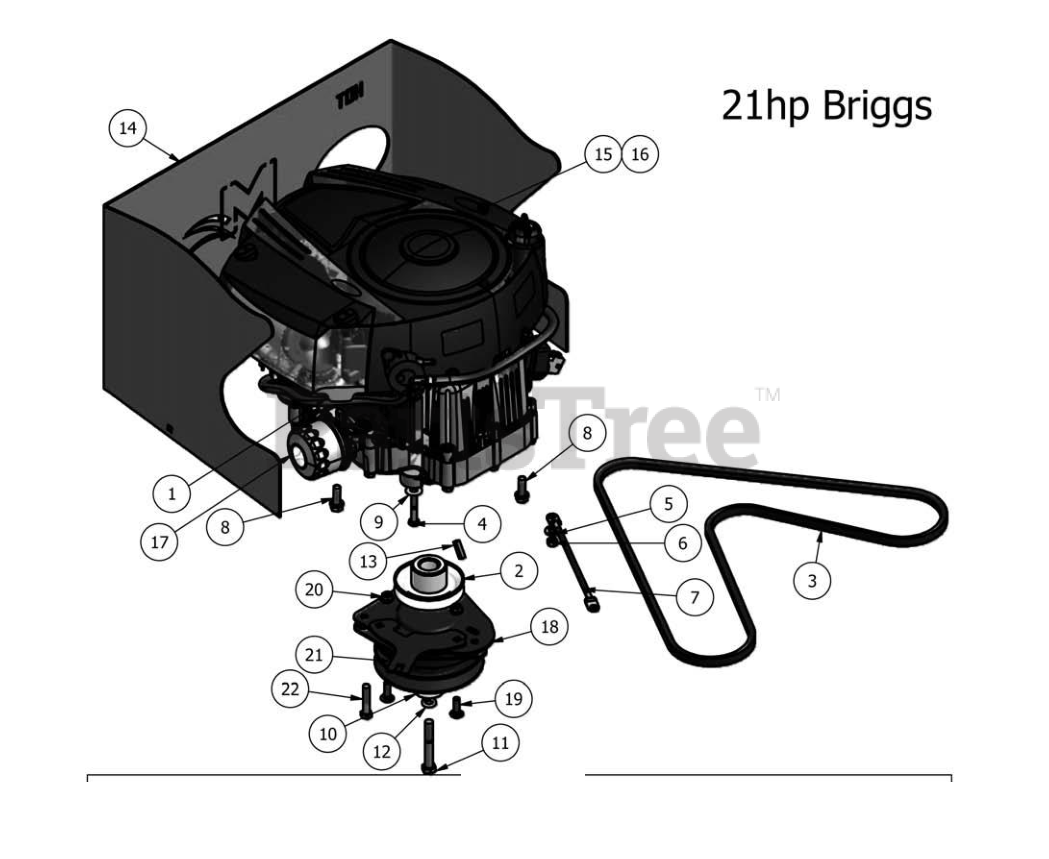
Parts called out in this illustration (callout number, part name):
1	21Hp Briggs Intek
2	3-3/4" Motor Pulley
4	3/8 x 3 1/2 Grade 5 Hex Bolt
5	5/16 Lock Washer Zinc
6	5/16-18 Hex Nuts Zinc
7	Ground Cable
8	3/8 x 1-1/8 Hex Washer Head Engine Bolt
9	5/16 USS Flat Washer Zinc
10	Spring Blade Cupped Washer
11	MZ Crank Shaft Bolt
12	7/16 Lock Washer Zinc
13	1/4" x 1" Key
14	Engine Rear Plate
15	Air Filter 21Hp MZ
16	Air Filter Precleaner for 21hp
17	Oil Filter 21Hp MZ
19	5/16" x 1" Carriage Bolt
20	5/16" Flange Nut
21	clutch Holder
22	3/8-16 x 3 1/2 Hex Bolt (Clutch Stop)
